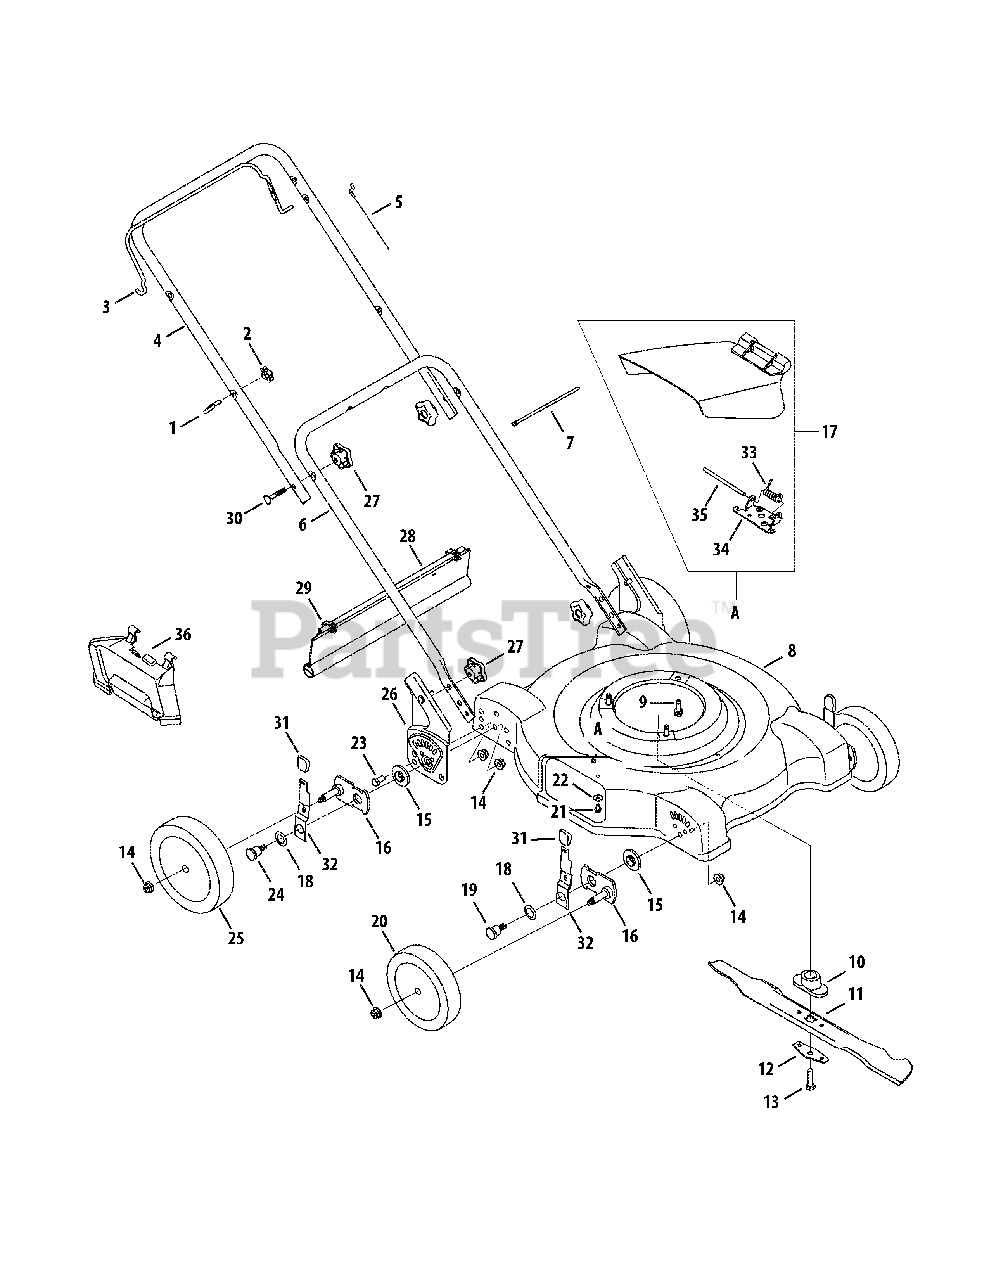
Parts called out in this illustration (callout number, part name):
1	Eye Bolt
2	Wing Nut
5	Control Cable
7	Cable Tie
9	TT Screw, 3/8-16 x 1.0
10	Blade Adapter
11	Standard Blade, 22"
11	Mulching Blade, 22"
12	Blade Bell Support
13	Screw, 3/8-24 x 1.5
14	Lock Nut, 3/8-16
15	Height Adjuster Bearing
16	Pivot Arm
17	Hinged Chute Deflector Assembly
18	Bell Washer, .760 OD x 1.25 OD
19	Shoulder Screw
20	Front Wheel, 7 x 1.8, Bar
21	TT Screw, 1/4-20 x .5
22	Bell Washer, .265 ID x .75 OD
23	Screw, 3/8-16 x .75
24	Shoulder Screw
25	Rear Wheel, 8 x 1.8, Bar
27	Star Knob
28	Trailshield
29	Hinge Clip
30	Carriage Bolt, 5/16-18 x 2
31	Knob
32	Lever
33	Torsion Spring
34	Chute Hinge
35	Hinge Pin
36	Mulching Baffle
